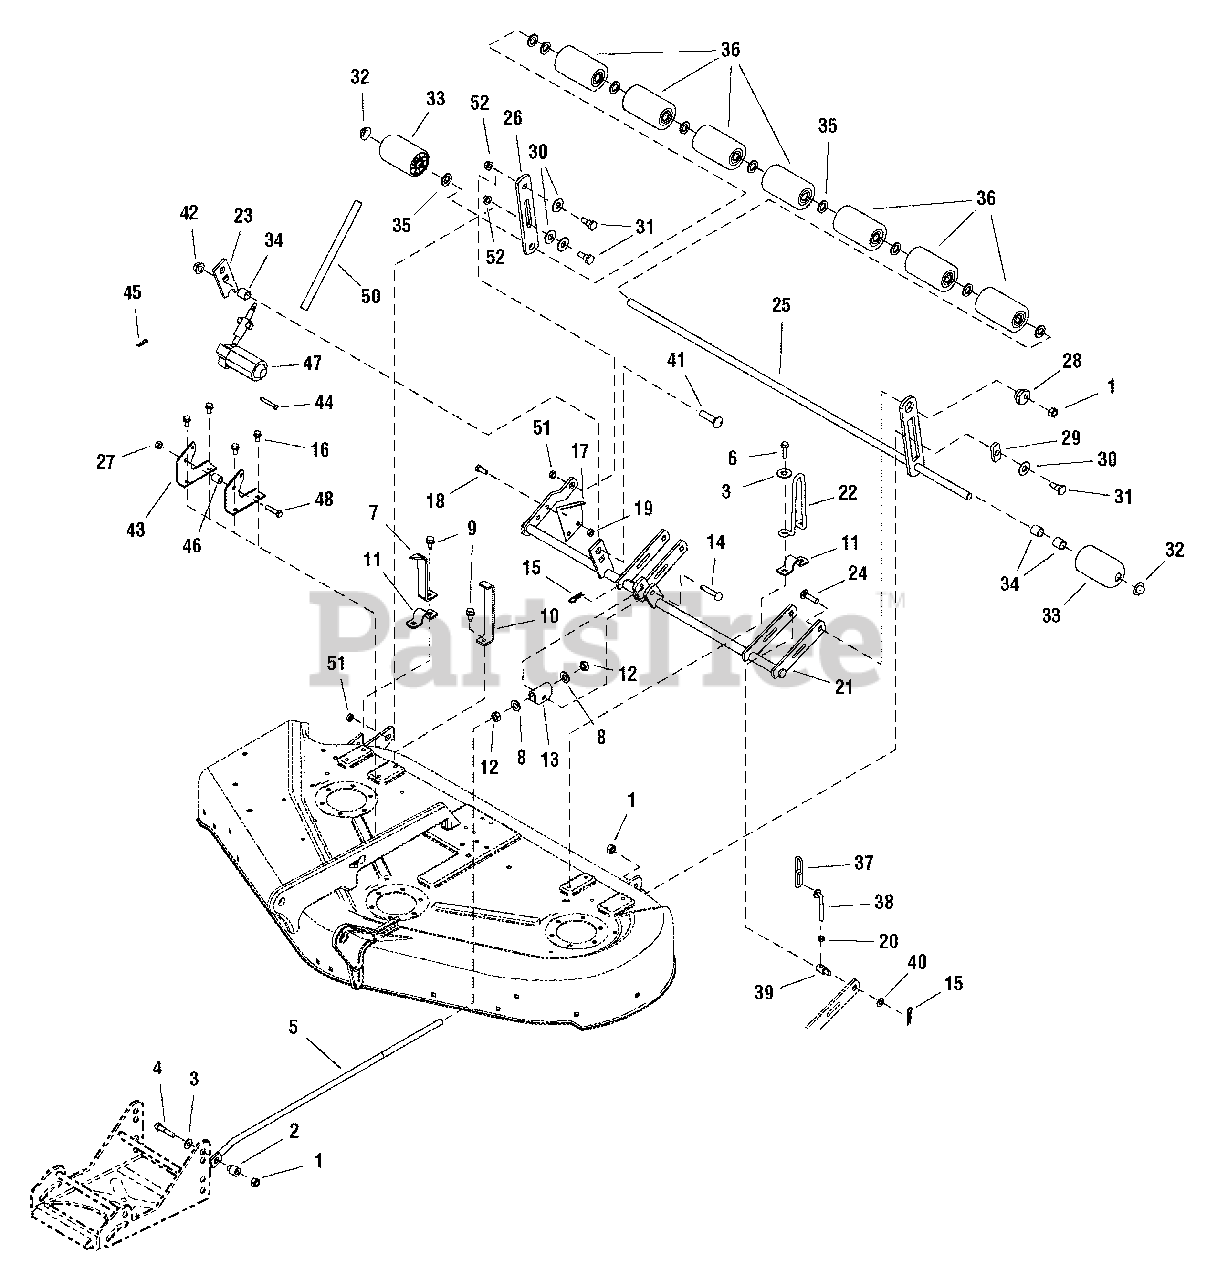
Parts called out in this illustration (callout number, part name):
1	NUT, Hex Toplock Spiral Lock Flange 3/8-16
2	SPACER, 3/8 x 3/4 x 15/16
3	WASHER, 3/8
4	CAPSCREW, Hex Head, 3/8-16 x 1-3/4
5	ROD, Adjustment
6	SCREW, Hex Washer Head Taptite 5/16-18 x 1-1/4
7	INDICATOR, Height of Cut
8	WASHER, 1/2
9	SCREW, Hex Washer Head Taptite 5/16-18 x 3/4
10	BRACKET, Up-Stop
11	STRAP, Roller E-Coat
12	NUT, Hex Jam 1/2-13
13	TRUNNION, Rod
14	PIN, Round Head Drilled 3/8 x 2
15	CLIP, Hair Pin
16	SCREW, Hex Washer Head Taptite 5/16-18 x 5/8
17	BRACKET, Height of Cut 16GA
18	SCREW, Hex Whiz Lock Flange 5/16-18 x 3/4
19	NUT, Hex Flange 5/16-18 Whiz Lock Small
20	NUT, Hex Jam 5/16-18
21	SHAFT ASSEMBLY, Rocker 44"
22	UP-STOP, 6-1/4 High
23	ARM, Rear 1/2 Thick
24	CARRIAGE BOLT, 3/8-16 x 1-1/2 G5
25	SHAFT & BAR ASSEMBLY, Roller 44"
26	BAR, Roller 5/16
27	NUT, Hex Flange 5/16-18 Whiz Lock Large
28	NUT, Hex Adjusting, .99 DIA .687
30	WASHER, 1/2
31	BOLT, Shoulder, 3/8-16 X 1.34
32	NUT, Push for 5/8 Diameter Stud Capped
34	SPACER, .66 ID
35	WASHER, 5/8
37	CHAIN, Link
38	ROD, Height Adjusting 5/16-18
40	WASHER, 3/8
41	CARRIAGE BOLT, 1/2-13 x 2 G5
42	NUT, Hex Toplock Flange 1/2-13
43	BRACKET, Mounting 10GA
44	PIN, Shear
45	CLIP, Hairpin
47	MOTOR, Electric
48	CAPSCREW, Hex Head 5/16-18 x 1-3/4 G5
50	TUBE, Flexible
52	NUT, Hex Flange 3/8-16 Machine Lock Large
